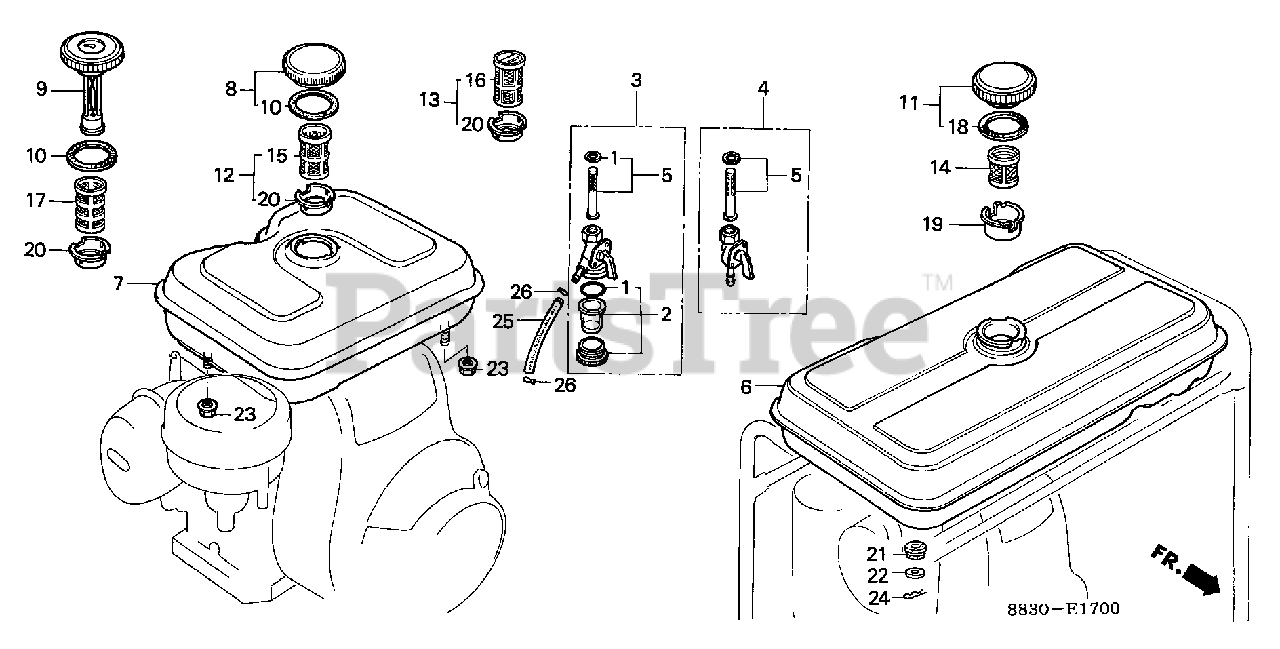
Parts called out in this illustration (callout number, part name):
1	GASKET SET, PETCOCK
2	CUP, FUEL STRAINER
2	CUP SET, FUEL STRAINER
3	PETCOCK ASSY.
5	SCREEN SET
6	TANK, FUEL Use up to Engine SN 1211507.
6	TANK, FUEL *NH31* Use from Engine SN 1211508.
7	TANK, FUEL *NH31* Use up to Engine SN 1121978.
7	TANK, FUEL *NH31* (MCKINLEY WHITE)
7	TANK, FUEL
8	CAP, FUEL FILLER (BLACK)
8	CAP, FUEL FILLER (BLACK) Use from Engine SN 2342663.
8	CAP, FUEL FILLER Use up to Engine SN 1543257.
8	CAP, SUB-TANK Use up to Engine SN 1543257.
9	GAUGE, FUEL (ENGLISH)
10	GASKET, FUEL FILLER CAP Use up to Engine SN 1543257.
10	GASKET, FUEL FILLER CAP Use from Engine SN 1543258.
11	CAP, FUEL FILLER (BLACK) Use from Engine SN 1518839.
11	CAP, FUEL FILLER Use from Engine SN 1211508 to 1518838.
11	CAP, FUEL TANK Use up to Engine SN 1211507.
12	FILTER, FUEL Use up to Engine SN 1543257.
14	FILTER, FUEL Use from Engine SN 1211508.
14	FILTER, FUEL Use up to Engine SN 1211507.
15	FILTER, FUEL
15	FILTER, FUEL Use up to Engine SN 1543257.
18	GASKET, FUEL FILLER CAP Use from Engine SN 1211508.
18	GASKET, FUEL FILTER Use up to Engine SN 1211507.
19	HOLDER, FUEL FILTER Use from Engine SN 1211508.
20	HOLDER, FUEL FILTER Use up to Engine SN 1543257.
20	HOLDER, FUEL FILTER
21	RUBBER, TANK CUSHION
23	NUT, FLANGE (6MM)
25	BULK HOSE, FUEL (4.5X3000) (4.5X70)
26	CLIP, TUBE (B8)
